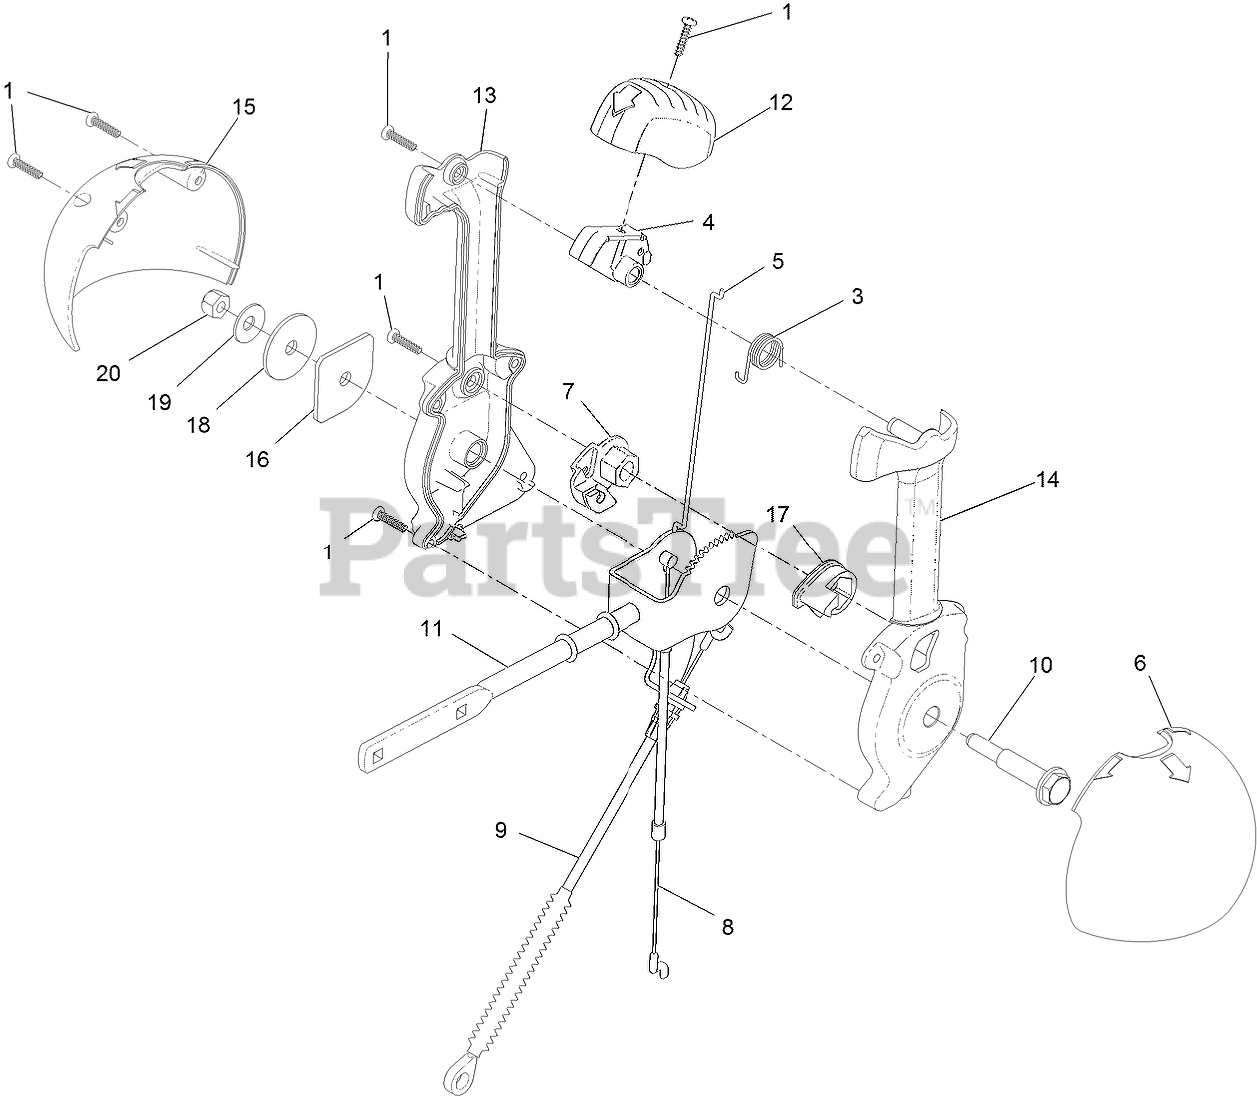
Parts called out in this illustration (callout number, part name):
1	SCREW-PPH
3	SPRING-TORSION
4	TRIGGER-LATCH
5	LINK-LATCH
6	COVER-LEVER, CHUTE (LH)
7	LEVER-CABLE, DEFLECTOR
8	CABLE-RELEASE, CHUTE
9	CABLE-CONTROL, DEFLECTOR
10	SCREW-SHOULDER
11	CHUTE CONTROL ROD
12	CAP-LEVER
13	LEVER-CONTROL, CHUTE (RH)
14	LEVER-CONTROL, CHUTE (LH)
15	COVER-LEVER, CHUTE (RH)
16	PLATE-FRICTION
17	PAWL-LATCH
18	WASHER-NYLON
19	WASHER-BELLEVILLE
20	NUT-LOCK, NI
